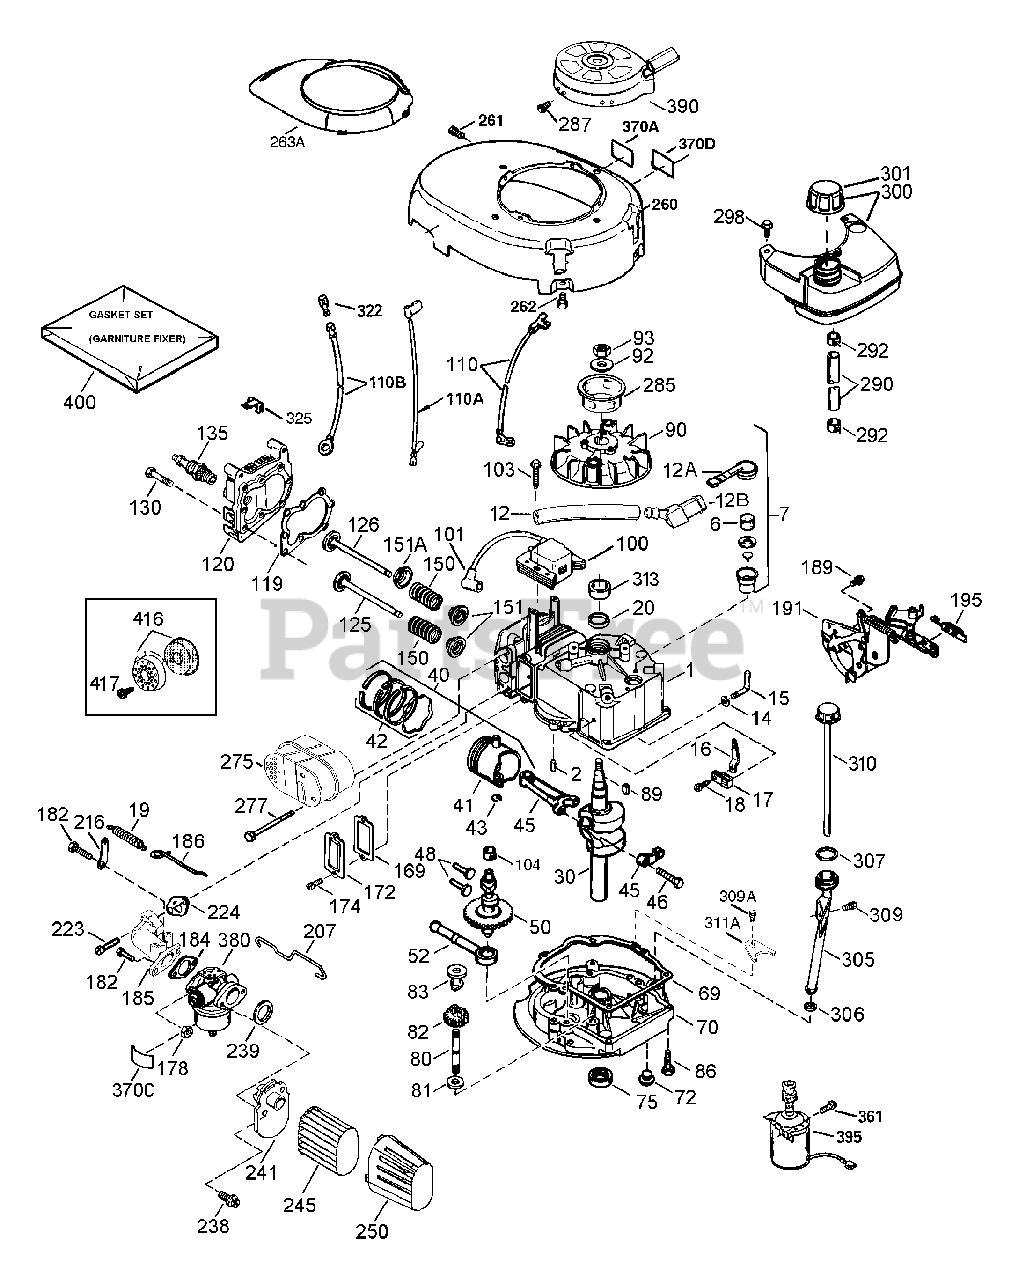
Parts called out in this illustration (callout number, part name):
313	Spacer
322	Connector Body
325	Wire Clip
361	Screw, 1/4-20 x 1/2"
370A	Lubrication Decal
370C	Primer Decal (3X)
370D	Caution Decal
380	Carburetor (Incl. 184)
390	Rewind Starter (NOTE: This engine could have been built with 590694 starter.)
395	Electric Starter Motor (12 Volt)
400	Gasket Set (Incl. Items Marked PK in Notes)
416	Spark Arrestor Kit (Incl. 417)(Optional)
417	Screw, 8-32 x 3/8' (Optional)
